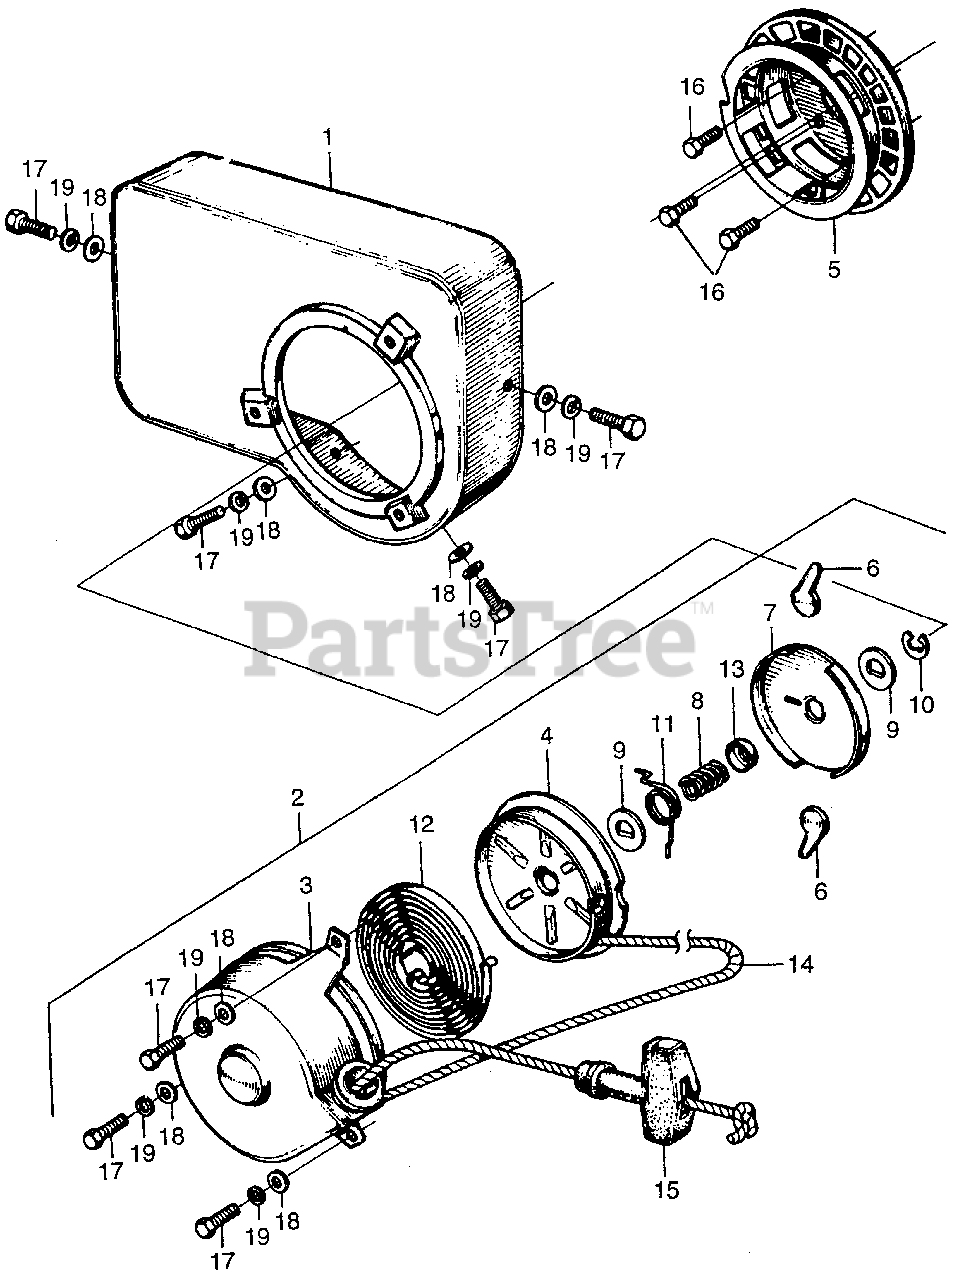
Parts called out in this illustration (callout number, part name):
1	COVER, FAN *PB6M* (CRYSTAL BLUE METALLIC)
1	COVER, FAN *R8* (BRIGHT RED)
2	STARTER ASSY., RECOIL *PB6M* (CRYSTAL BLUE METALLIC) (NOT AVAILABLE)
2	STARTER, RECOIL *R8* (BRIGHT RED) (NOT AVAILABLE)
3	CASE, RECOIL START *PB6M* (CRYSTAL BLUE METALLIC)
3	CASE, STARTER *R8* (BRIGHT RED) (NOT AVAILABLE)
4	PULLEY, STARTER (NOT AVAILABLE)
5	PULLEY, RATCHET (NOT AVAILABLE)
6	RATCHET, STARTER
7	PLATE, FRICTION
8	SPRING, FRICTION (NOT AVAILABLE)
9	WASHER, STARTER
11	SPRING SET
12	SPRING, STARTER
13	COVER, SPRING
14	ROPE, RECOIL STARTER (#5X55")
15	KNOB, STARTER
16	BOLT, HEX. (5X8)
17	BOLT, HEX. (6X12)
18	WASHER, PLAIN (6MM)
19	WASHER, SPRING (6MM)
